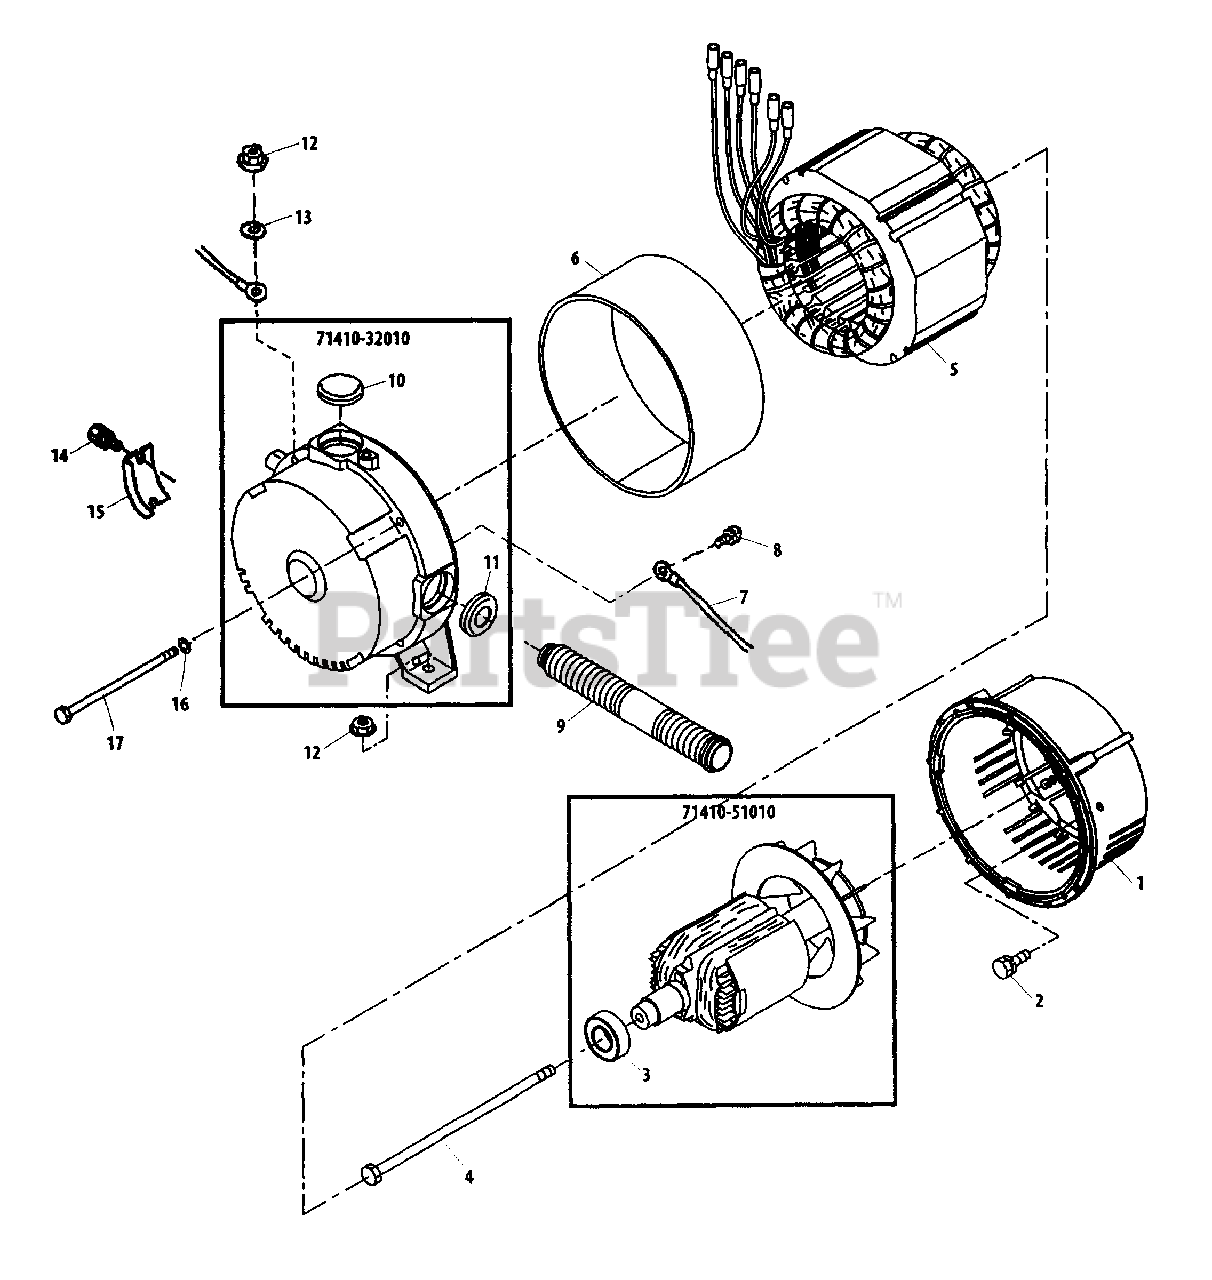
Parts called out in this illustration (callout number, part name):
1	COVER - FRONT
2	BOLT - 8X20
3	BEARING, BALL - 6205
6	STATOR COVER
7	LEAD - ANTI-STATIC
8	SCREW - 4X6
9	FLEXIBLE TUBE
12	NUT - 8 -- FLANGE
13	WASHER - 8
14	BOLT - 5X12
15	COVER, BRUSH
16	LOCKWASHER - 8
17	BOLT - 8X90
71410-32010	COVER ASSY - REAR
71410-51010	ROTOR ASSY
